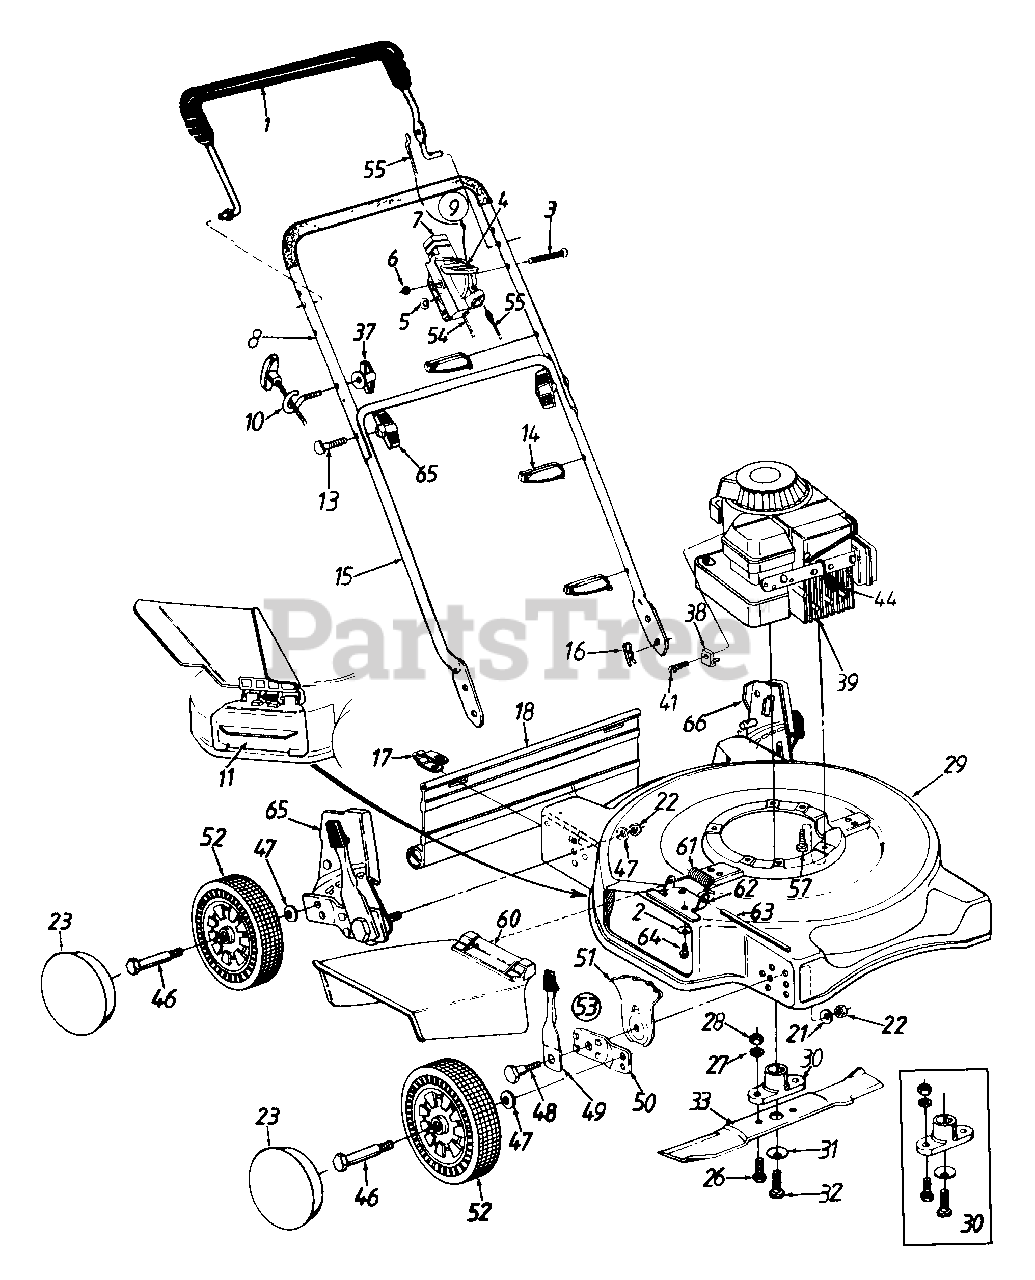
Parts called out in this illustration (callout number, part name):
1	Control Handle Ass'y.
2	Bell-Wash. 1/4" I.D.
3	Oval C-Sunk Mach. Scr.
4	Throttle Lever
5	Spr. Wash..66" I.D.
6	Hex L-Nut 1/4-20 Thd.
7	Throttle Body
10	Rope Guide
11	Mulching Plug
13	Curved Hd. Bolt 5/16-18 x 2" Lg.
14	Cable Tie
16	Hairpin Cotter
17	Hinge Clip
18	Rear Flap
21	Bell-Wash..39" I.D. x 1.38"
22	Hex Nut 3/8-16 Thd.
23	Hub Caps
26	Hex Bolt 3/8-24 x 1" Lg.
27	L-Wash. 3/8" I.D.
28	Hex Nut 3/8-24 Thd.
31	Bell-Wash..39" I.D.
32	Hex Bolt 3/8-24 x 1.5" Lg.
33	20" Blade
37	Wing Nut 1/4-20 Thd.
38	Cable Clamp
39	Engine
41	Hex Wash. Hd. Tap Scr #10-32 x .62" Lg.
44	Spark Plug Boot
46	Axle Bolt
47	Bell-Wash..400" I.D x.88"
48	Shld. Bolt 50" Dia x .357"
49	Spring Lever Ass'y. w/Knob
51	Height Adj. Plate
52	Wheel Ass'y. Comp.
53	Height Adj. Ass'y. Comp.- R.F.
54	Throttle Cable - 51"
55	Control Cable - 39"
57	Hex L-Wash. Hd. Scr. 3/8-16 x 1.0" Lg.
60	Chute Deflector Ass'y.
61	Torsion Spring
62	Adapter Plate
63	Hinge Pin
64	Hex Self-Tap Scr. 1/4-20 x .5"
